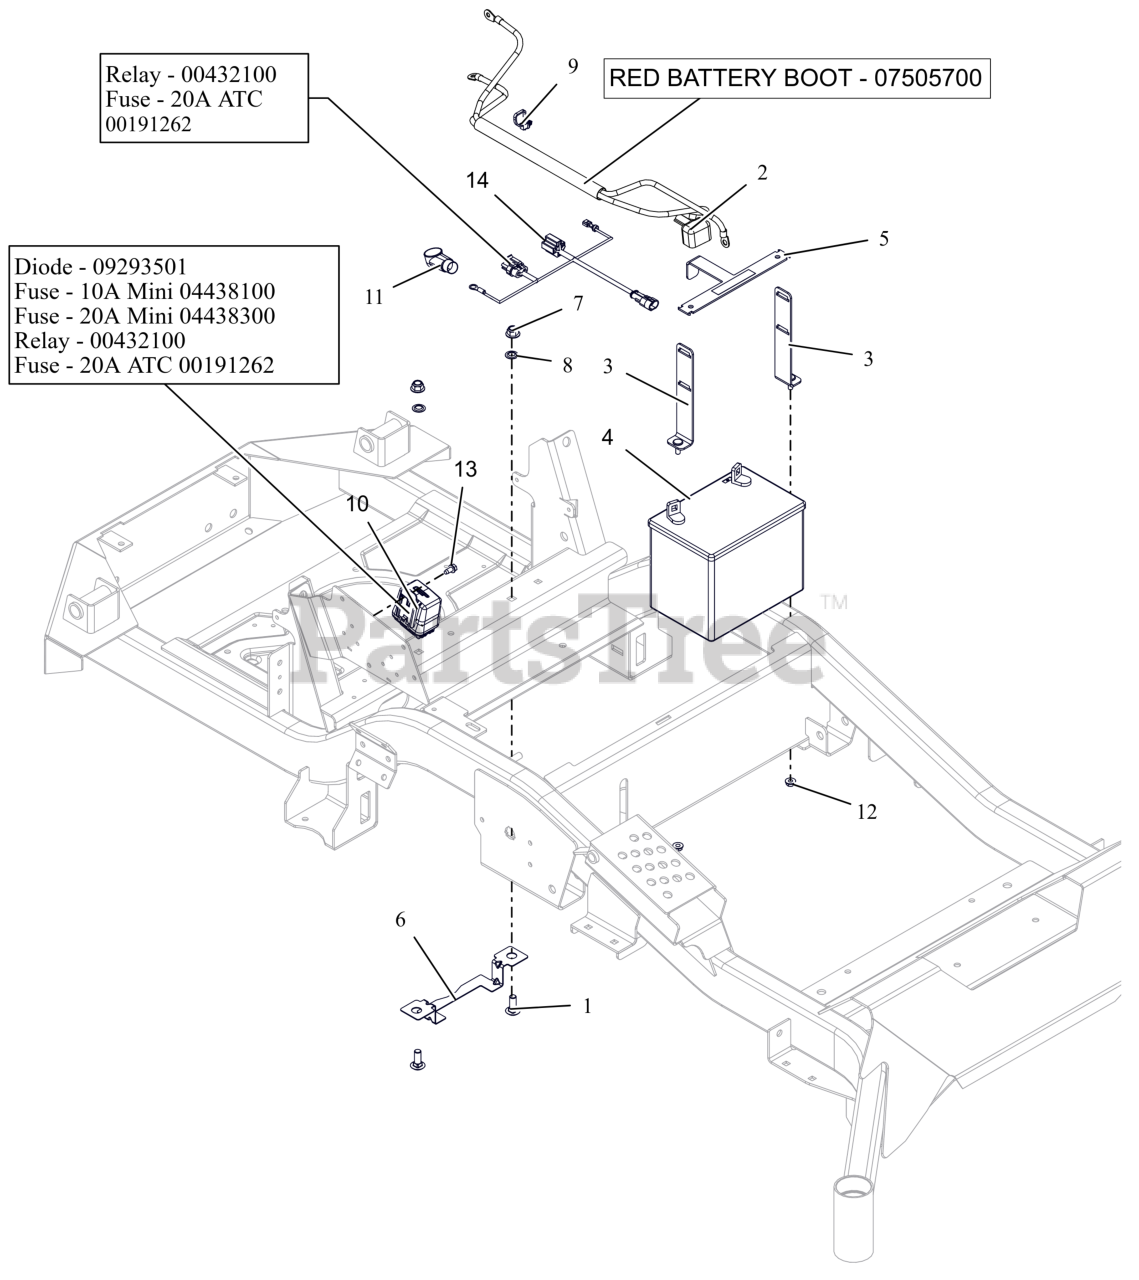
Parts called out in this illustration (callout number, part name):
1	BLT, RHSN .38-16X1.00 G5 ZCC
2	HARNESS, BATTERY HD
2	INSULATOR
3	WMT,BATTERY MOUNT HOLD DOWN
4	BATTERY, 300 CCA 10U1L
5	BRKT, BATTERY TIE DOWN
6	GUARD, ELECTRICAL HARNESS
7	NUT,NYL-FLG .38-16 GF ZCC
8	NUT-PUSH .38 DIA. PAL ZINC
9	CABLE TIE W/ TREE (.25 HOLE)
10	HARNESS, WIRE
10	DIODE, CONNECTOR SHELL
10	FUSE,10 AMP MINI-ATC
10	FUSE,20 AMP MINI ATC
10	RELAY,MICRO5 TERML W/RESISTOR
10	FUSE, 20 AMP BLADE S/O
11	BOOT, .65ID POS
12	NUT-LK-TOP-FLG .250-20 GF ZCC
13	SCR-TAP .25-20X.50 HWH ZCC
14	HARNESS, STARTER ADAPTOR
14	RELAY,SEALED W/DIODE
14	FUSE, 20 AMP BLADE S/O
